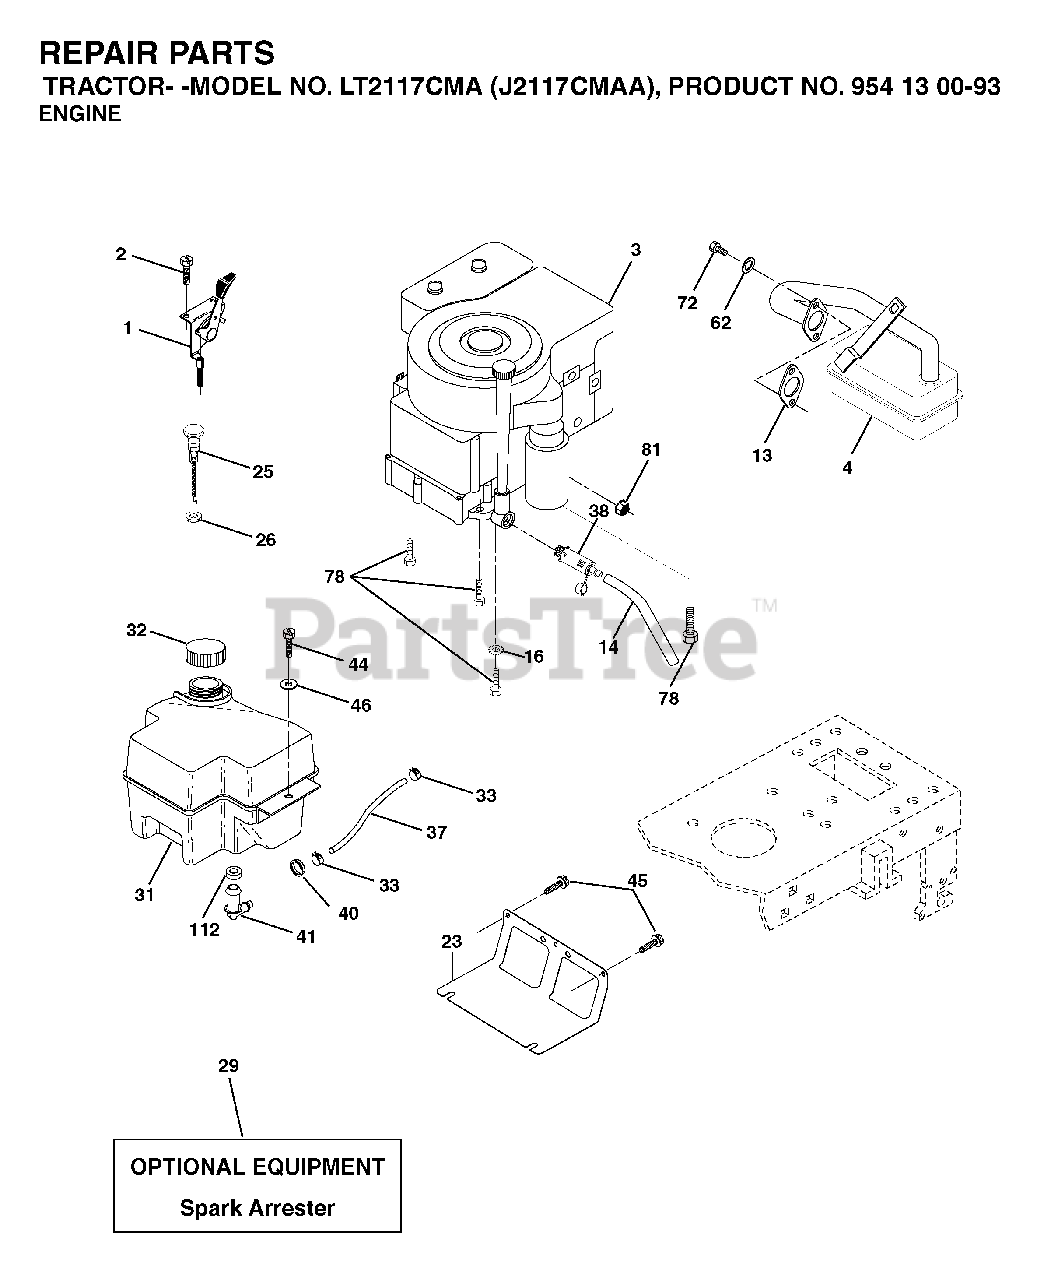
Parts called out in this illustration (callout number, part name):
1	CONTROL.TH/CK.C.
2	SCREW
13	REPL BY 532 27 22-93
14	TUBE, DRAIN OIL ASM.
16	LOCKWASHER
23	SHEILD.BROWNING.DBR.GUARD
26	NUT KEPS 3/8 - 24 UNF
29	ARRESTER SPARK (OPTIONAL)
31	GAS TANK 2GAL
32	FUEL CAP
33	HOSE CLAMP
37	LINE.FUEL.20
38	PLUG DRAIN OIL EASY
40	GROMMET T
41	STEM FUEL TANK
44	SCREW HEXWSHR 1/4-20X3/4
45	SCREW, 3/8-16X3/4
62	LOCKWASHER
72	SCREW
78	SCREW.3/8-16
81	NUT
112	BUSHING OUTLET T
